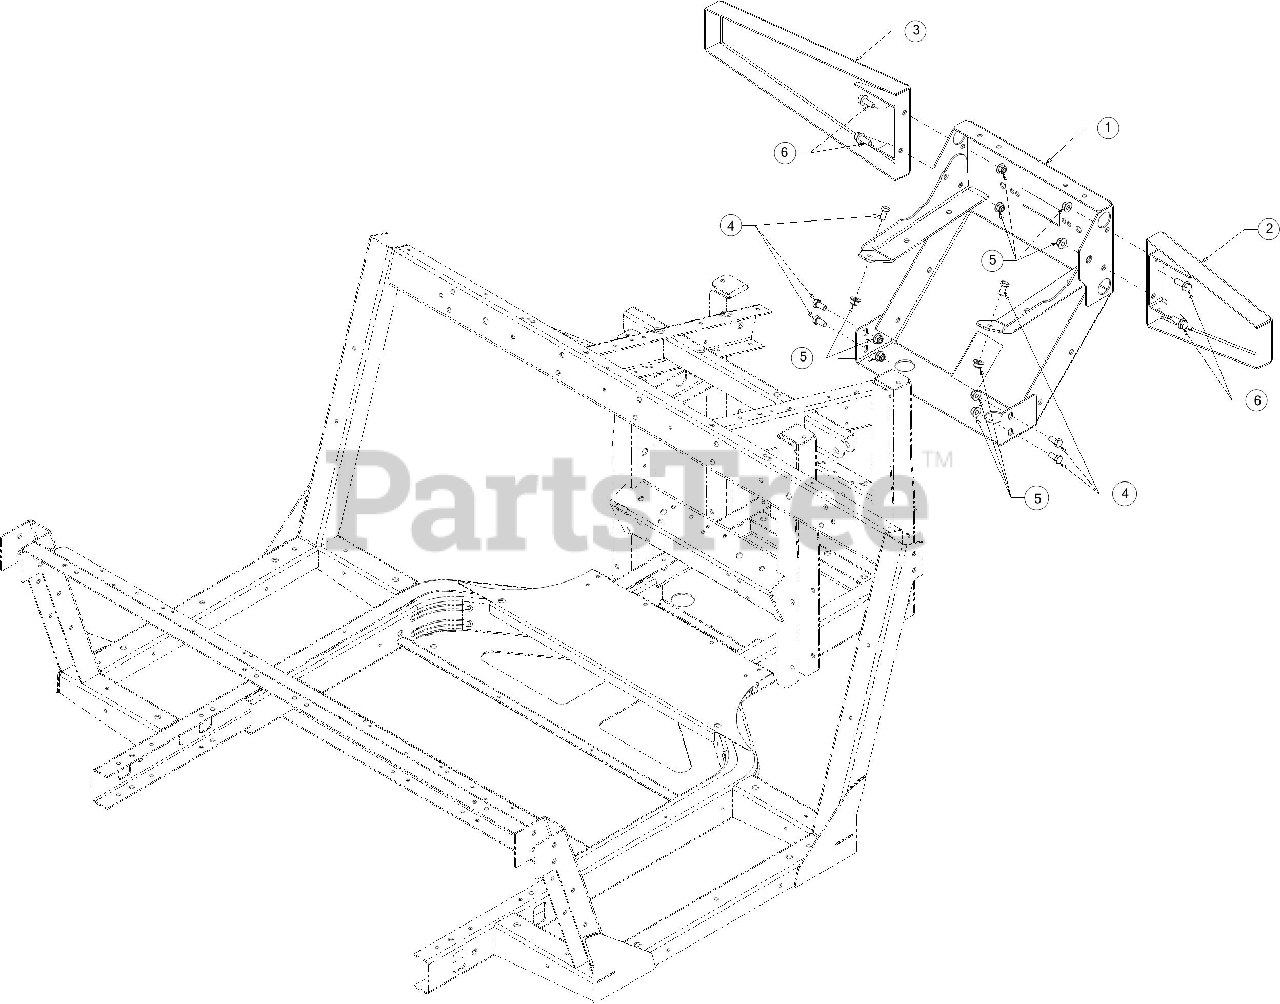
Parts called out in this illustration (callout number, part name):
1	FRONT BUMPER ASSEMBLY
2	BUMPER ASSEMBLY (RH)
3	BUMPER ASSEMBLY (LH)
4	HEX SCREW 3/8-16 x .75
6	HEX SCREW 3/8-16
